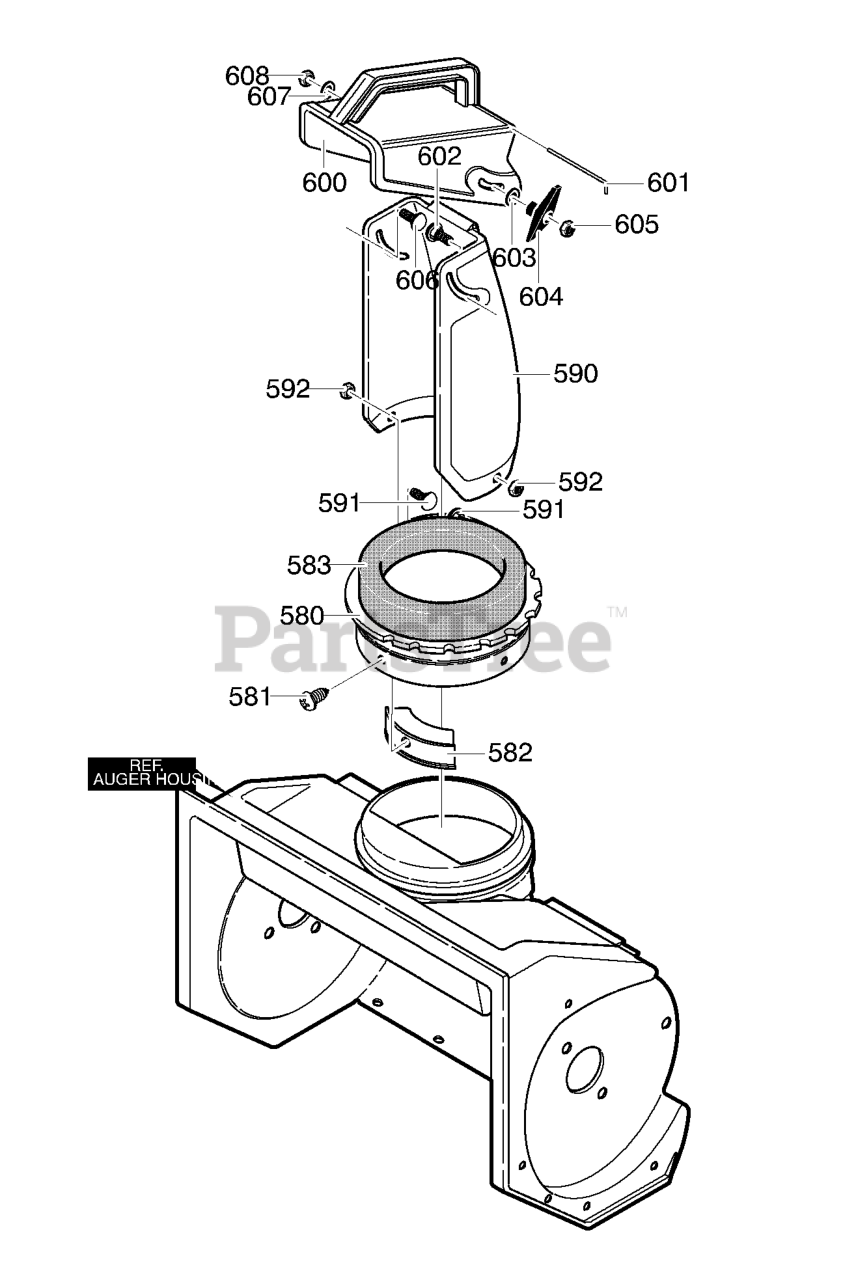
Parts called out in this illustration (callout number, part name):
580	RING, CHUTE
581	SCREW, #10X.50
582	GUIDE, CHUTE
583	DONUT FOAM
590	CHUTE ASSY.
591	SCREW 1/4-20X.50
592	NUT, 1/4-20
602	BOLT, 5/16-18X1.25 CARR.
603	WASHER, FLAT .349X.69X.066
604	KNOB, T
605	NUT, 5/16-18
606	SCREW, 5/16-18 x 0.75
607	WASHER, FLAT .349X.69X.066
608	NUT, 5/16-18
